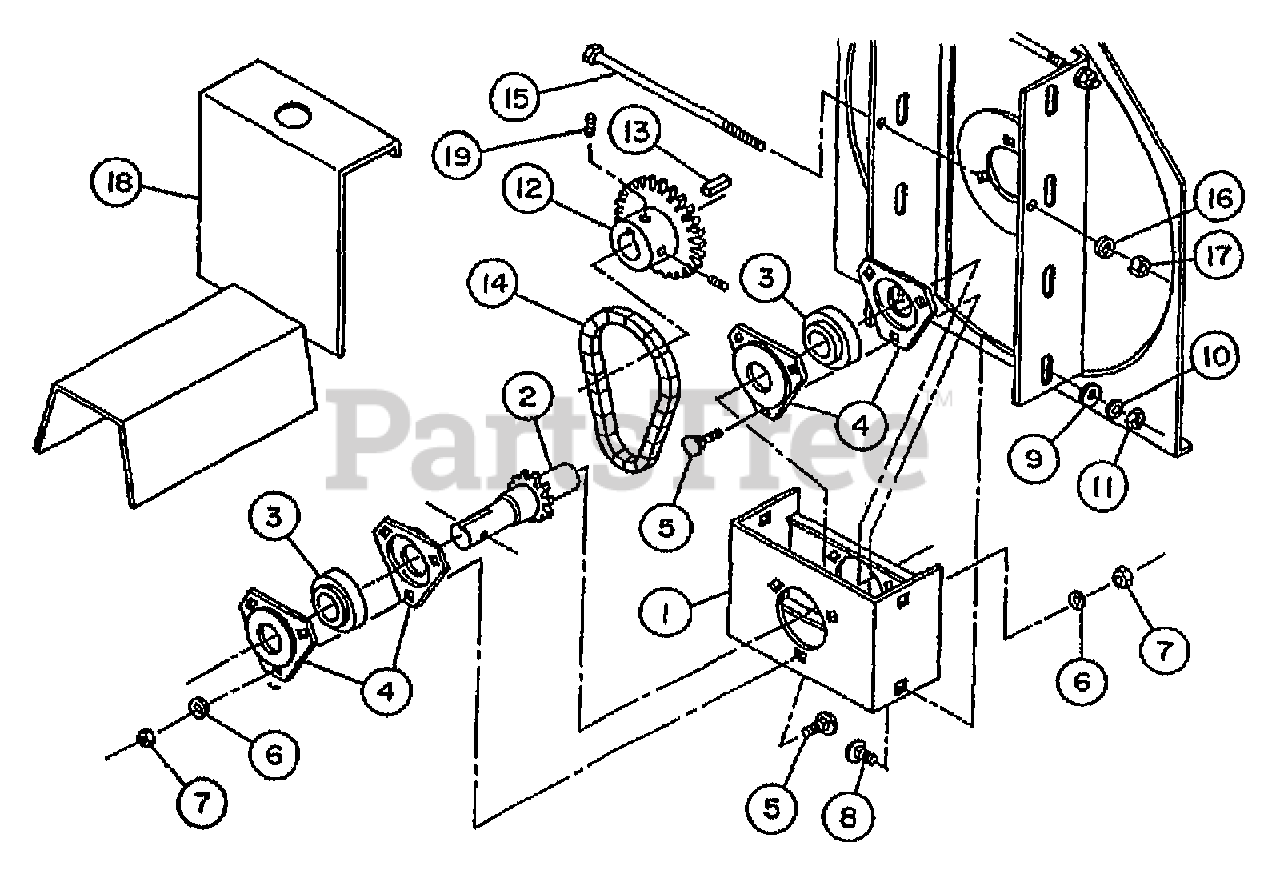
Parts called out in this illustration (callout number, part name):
1	BOX-REDUCTION
2	SHAFT W/SPROCKET
5	RIVET-POP
6	WASHER-LK .312 ZP
7	NUT-HEX 5/16-18 ZP
8	SCR-CARR 5/16-18X.75 G2 ZP
9	WASHER-LK .312 ZP
10	WASHER-FLAT 3/8 SAE
11	NUT-HEX 5/16-18 ZP
12	SPROCKET
13	KEY-.25 SQ X 1.0
15	BOLT-1/4X7 1/2
16	WASHER-LK .25 ZP
17	NUT-HEX 1/4-20 ZP
18	COVER-PTO
19	SCR SET 5/16-18X.50
